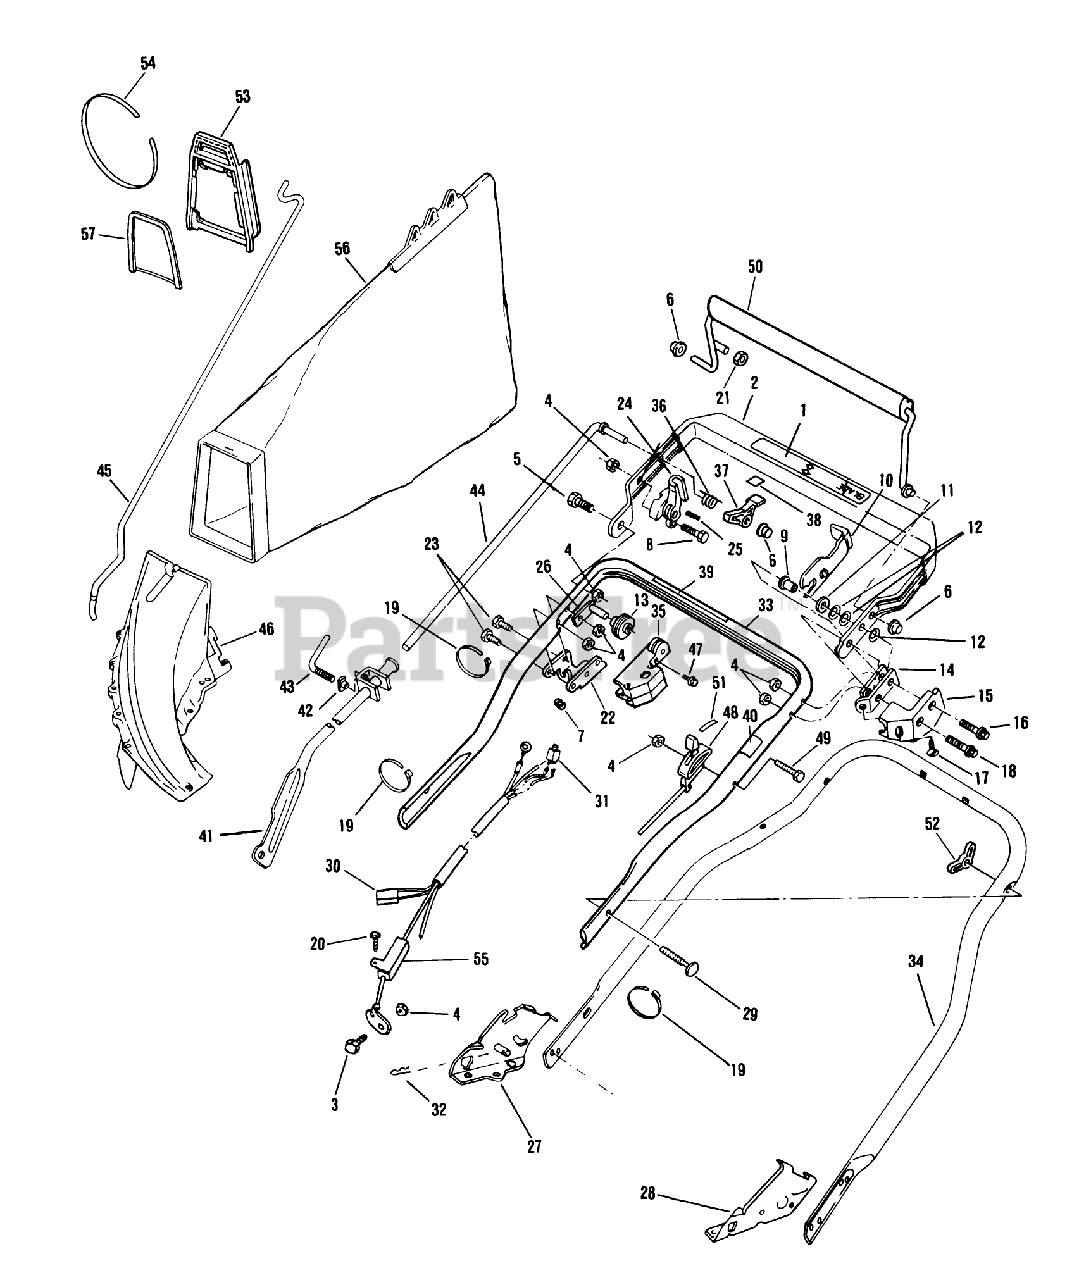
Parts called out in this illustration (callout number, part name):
4	LOCKNUT E
5	BOLT
7	RET. RING
9	SPACER
11	WASHER M
13	PULLEY PL
14	DOWN STOP
15	LOCKOUT GUARD
16	SCREW
17	SCREW F
18	BOLT SHOU
20	SCREW-HH
21	NUT ACORN
27	BRACKET ASM - HANDLE, SP, RH
28	BRACKET ASM - HANDLE, SP, LH
29	BOLT QUALITY
32	HAIR PIN
45	ROD GRASSBAG
47	SCREW LAWRENCE
48	CONTROL THROT WES
52	NUT-WING
53	CHUTE - ADAPTER
55	CONTROL CABLE
56	ORDER 89816 THRU WHOLE GD
57	CHUTE BRACE
